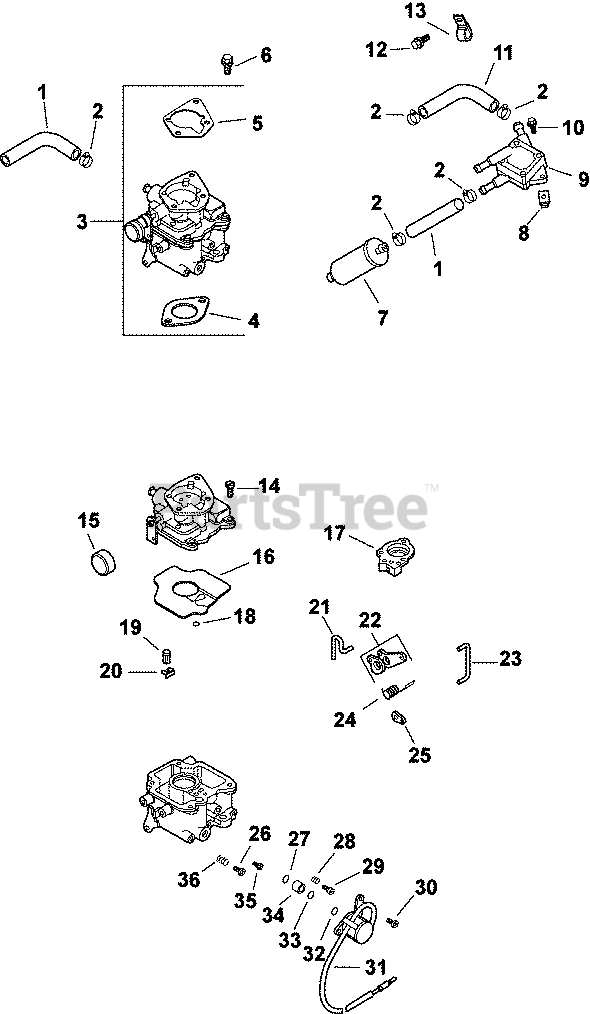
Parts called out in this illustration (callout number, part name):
1	HOSE,LW PERM.FUEL 24.00"-USE 25 111 81-S
2	CLAMP, HOSE (KM)-USE 25 237 31-S
3	KIT,CARB(KEIHIN) W/GASKETS-KSF
4	GASKET, CARBURETOR
5	GASKET, AIR CLEANER BASE
6	SCREW, FLG M6X1.0X25
7	FILTER, FUEL
8	NUT, PLASTIC - BLACK
9	PUMP, FUEL
10	SCREW, TAP M6X1.7X18
11	LINE, FLEXIBLE FUEL 15 1/2"
12	SCREW, FLG M6X1.0X12
13	CLIP, CABLE - USE 24 154 10-S
14	SCREW, CARBURETOR BODY
15	CAP, CHOKE LEVER
16	GASKET, CARBURETOR BODY
17	HOUSING, PUMP
18	O-RING, SLOW JET
19	VALVE, INLET NEEDLE
20	CLIP, INLET NEEDLE VALVE
21	LINKAGE, ROD
22	LEVER, LINK
23	LINKAGE, ROD
25	LEVER, LINK
26	JET, MAIN
27	O-RING, SOLENOID
28	SPRING, IDLE NEEDLE
29	NEEDLE, IDLE
30	SCREW, SOLENOID
31	SOLENOID ASSEMBLY
32	O-RING, SOLENOID
33	O-RING, SOLENOID
34	SEAT, SOLENOID
35	SCREW, IDLE
36	SPRING, IDLE SPEED ADJ SCREW
